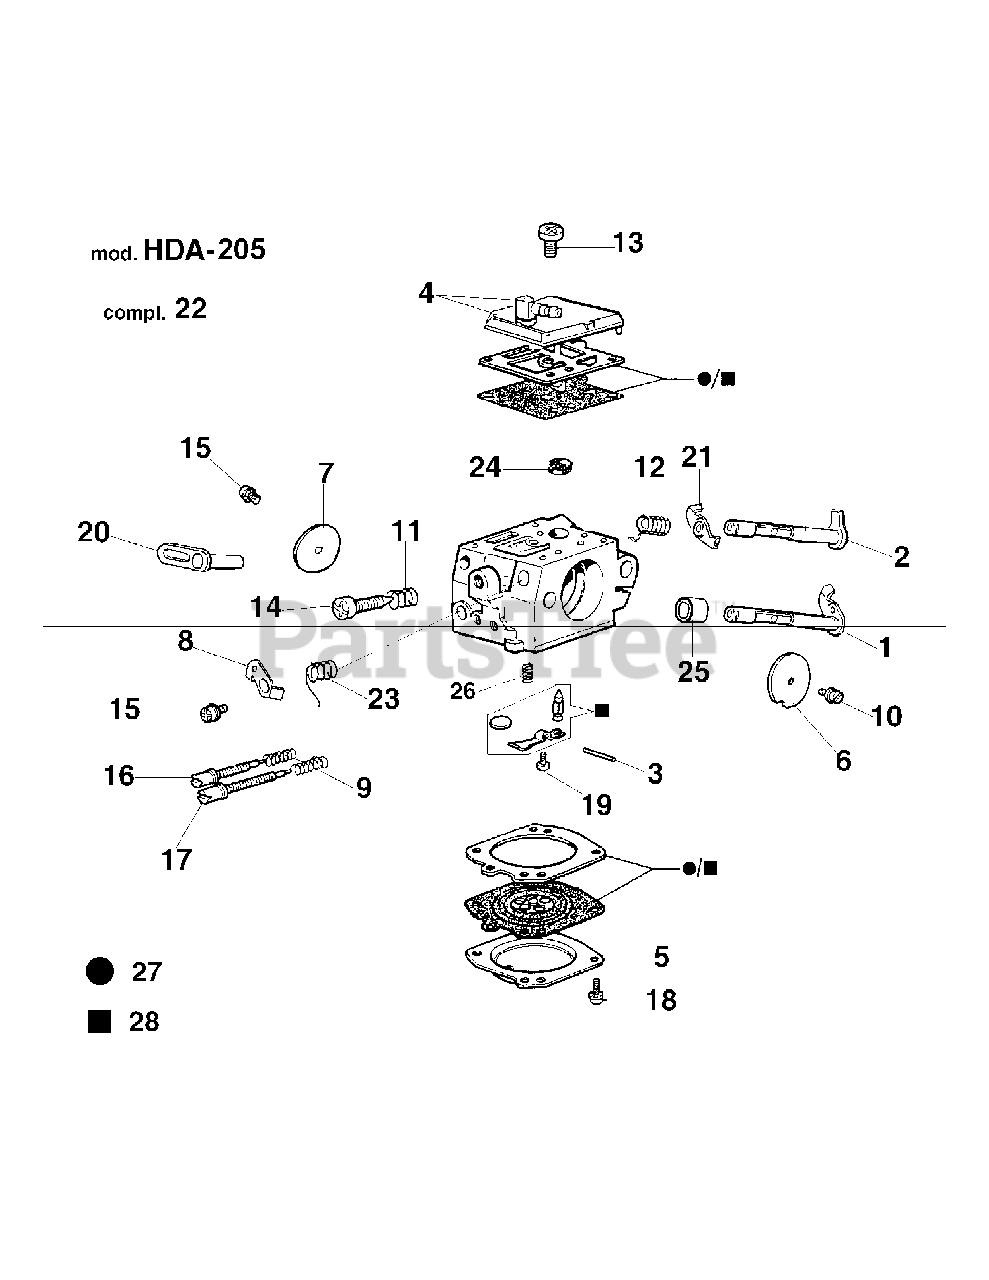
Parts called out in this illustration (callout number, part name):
1	THROTTLE SHAFT
2	STARTER SHAFT
6	THROTTLE VALVE
7	CHOKE SHUTTER
8	THROTTLE LEVER
20	STARTER LEVER
27	DIAPH./GASKETSET
